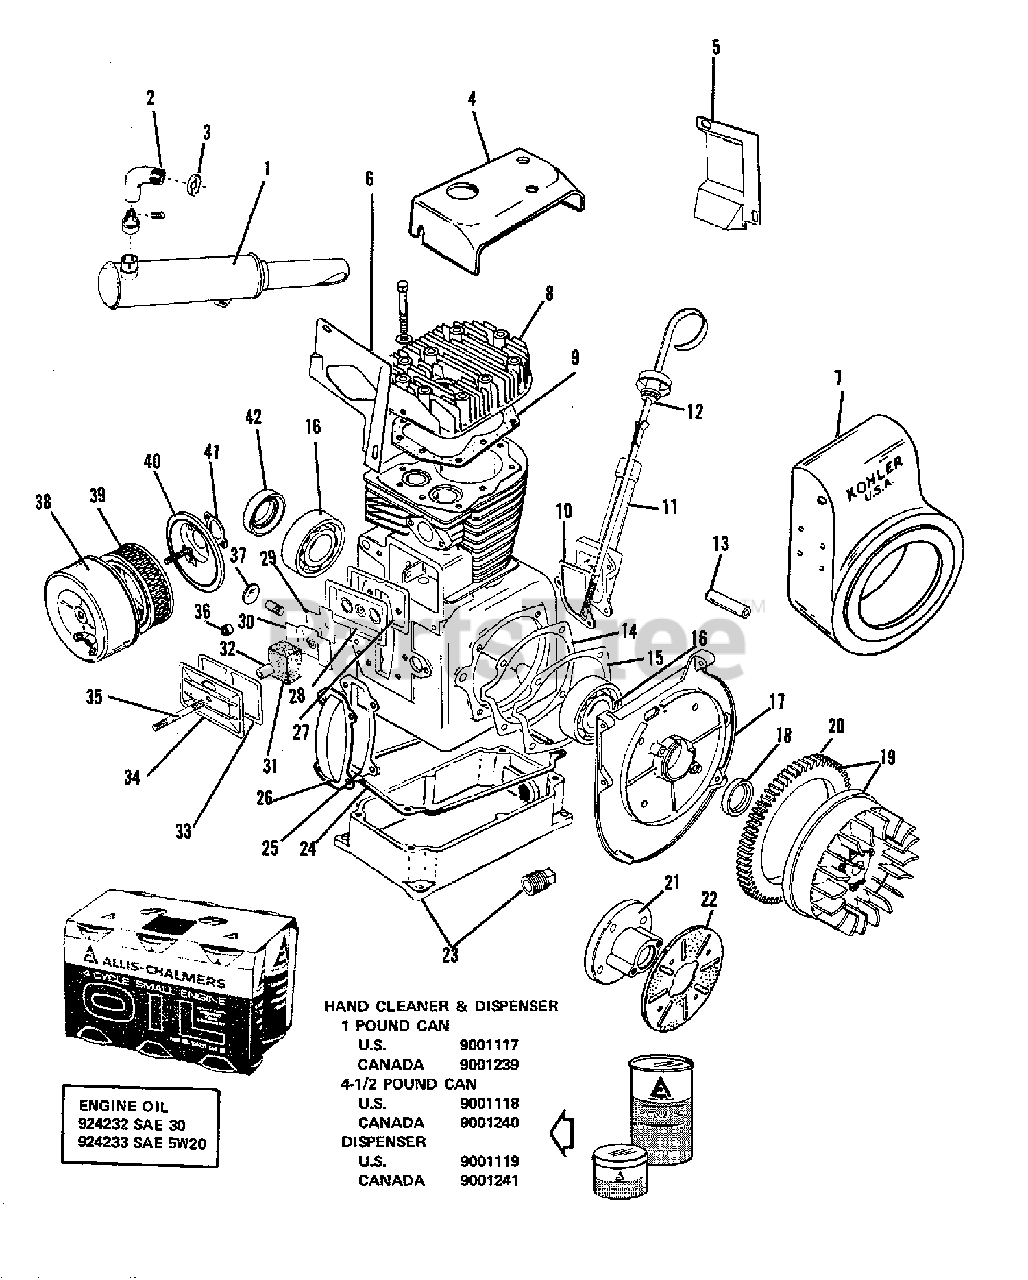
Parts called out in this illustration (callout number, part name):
1	*MUFFLER ASSEMBLY
2	*ELBOW, Exhaust
3	*NUT, Lock
4	BAFFLE, Head
4	SCREW, 1/4NC x 1/2
5	BAFFLE, Cylinder
6	BAFFLE, Side Air
7	HOUSING, Blower
7	SCREW, 1/4NC x 3/4
8	HEAD, Cylinder (10 H.P.)
8	HEAD, Cylinder (12 H.P.)
8	HEAD, Cylinder (14 H.P.)
8	SCREW, 3/8NC x 1-1/2
9	GASKET, Head
10	GASKET, Dipstick Tube
11	TUBE ASSEMBLY, Dipstick Oil Guage
11	LOCKWASHER, #10 Intake Tooth
12	DIPSTICK ASSEMBLY, Oil Level
13	SHAFT, Stub Crankcase
14	GASKET, .010 (Use as Required)
15	GASKET, Bearing Plate
16	BEARING ASSEMBLY, Bail
17	PLATE ASSEMBLY, Bearing
18	SEAL, Front Oil
19	FLYWHEEL ASSEMBLY, (Includes Item 20)
20	GEAR, Ring
21	ADAPTER, Front Drive
21	SCREW, 3/8 NC 7/8
21	LOCKWASHER, 3/8
21	WASHER, 1/4
21	NUT, Lock 5/8 NC
21	SCREW, 1/4 NC x 5/8 (Truss head)
21	LOCKWASHER, 1/4 (Internal Tooth)
22	SCREEN, Grass
23	PLUG, Pipe, 3/4
23	CAPSCREW, 3/8 NC x 1-1/4
23	CAPSCREW, 3/8 NC x 1-1/2
23	LOCKWASHER, 3/8
23	NUT, 3/8
24	GASKET, Oil Pan
25	GASKET, Camshaft Cover
26	COVER, Camshaft
26	SCREW, 1/4 NC x 1/2
27	GASKET, Breather Plate
28	PLATE, Breather
29	REED, Breather
30	BAFFLE, Breather
31	FILTER, Breather
32	SEAL, Breather
33	GASKET, Breather Valve Cover
34	COVER, Valve Breather
35	STUD, Breather
35	LOCKWASHER, 1/4
35	NUT, 1/4 NC
36	BEARING, Needle
37	PLUG, Expansion
38	COVER, Air Cleaner
39	ELEMENT, Air Cleaner
40	BASE ASSEMBLY, Air Cleaner
40	NUT, Wing
41	GASKET, Air Cleaner
42	SEAL, Rear Oil
42	GASKET SET, Engine, (Includes Items 9, 10, 14, 15, 18, 24, 25, 27, 32, 33, 42; CARBURETOR, FUEL PUMP & AIR CLEANER GASKETS)
